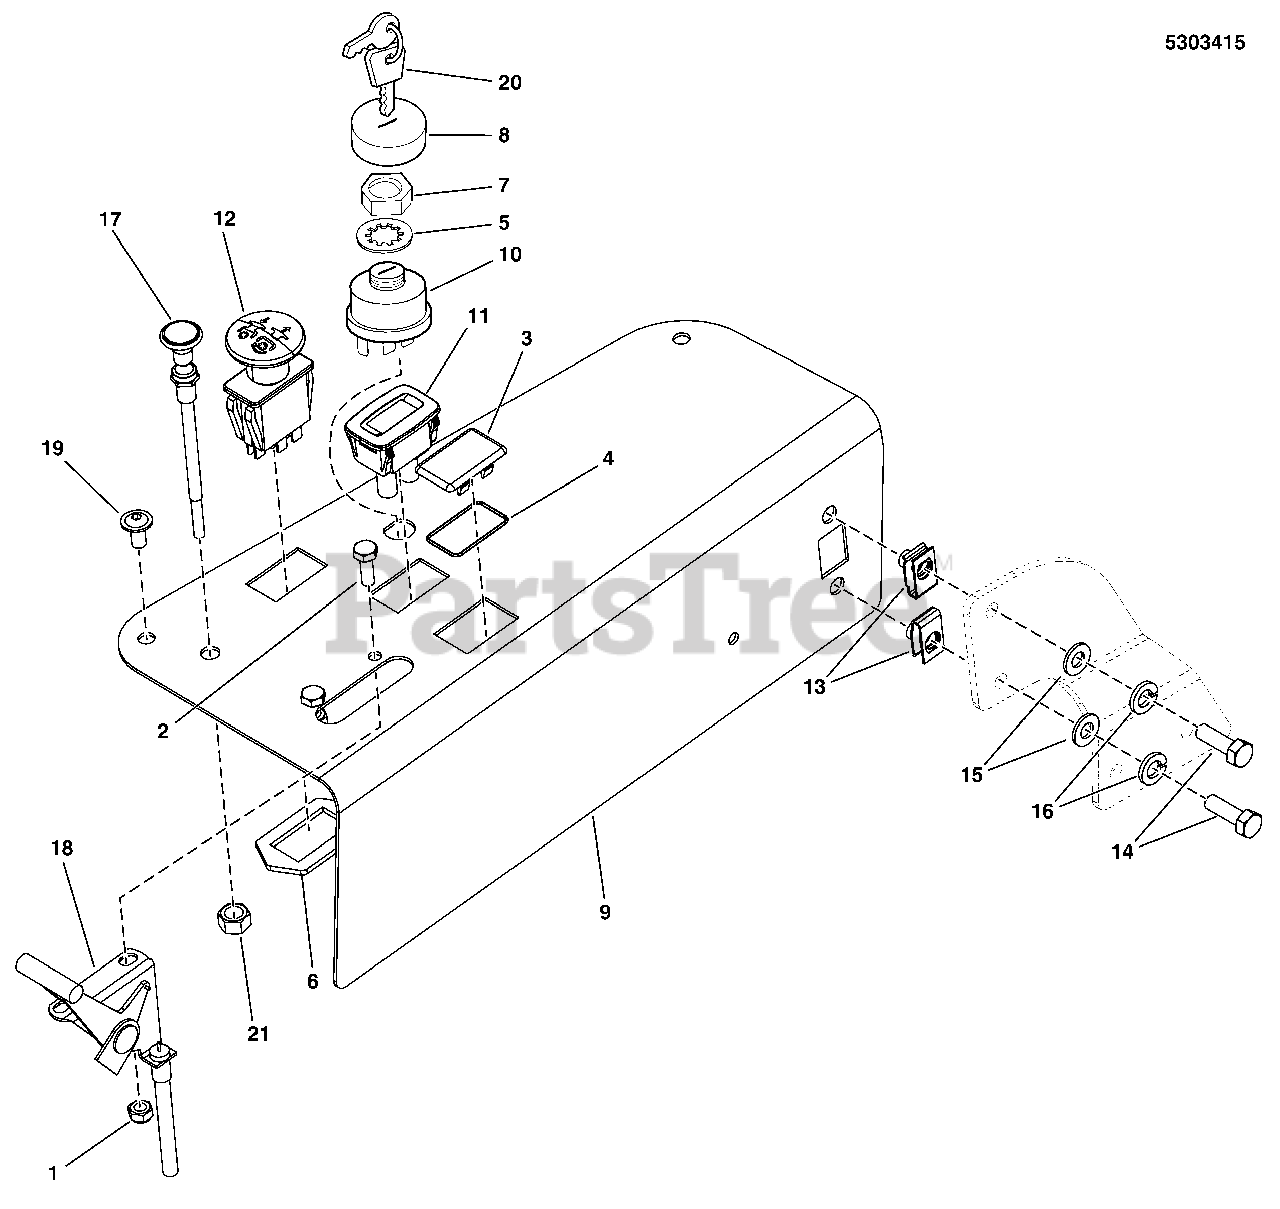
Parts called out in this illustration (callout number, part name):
1	NUT, Hex, Nylon Lock, 1/4-20
2	CAPSCREW, Hex Head, 1/4-20 x 3/4 (stiffener to top of cover)
3	PLUG, Hole, Electric Lift (Hydro models only)
4	O-RING, 7/8" ID X 1/16" W
5	LOCKWASHER, Internal Tooth, 5/8 Thin
6	RING, SWITCH RETAINER, PTO
7	NUT, Hex Flange, 5/8-32 IGN SW DIE CAST
8	COVER, Ignition Switch
9	PLATE, CONTROL PANEL, S550 - BLK
10	SWITCH ASSEMBLY, Ignition Indak No Keys/Hdwr
11	HOUR METER, ASSEMBLE
12	SWITCH, Blade Engage
13	CLIP, BODY , 5/16-18 FOR 7 GA.
14	CAPSCREW, Hex Head, 5/16-18 X 1
15	WASHER, 5/16
16	WASHER, Flat
17	CABLE, CHOKE CONTROL, 51 (Z)
18	CABLE, Throttle Control, 40"
19	SCREW, ALLEN HEAD 1/4-20 X .500 ZINC PHOS
20	KEYS, Ignition
21	NUT, 3/8-24 HEX JAM (SV)
